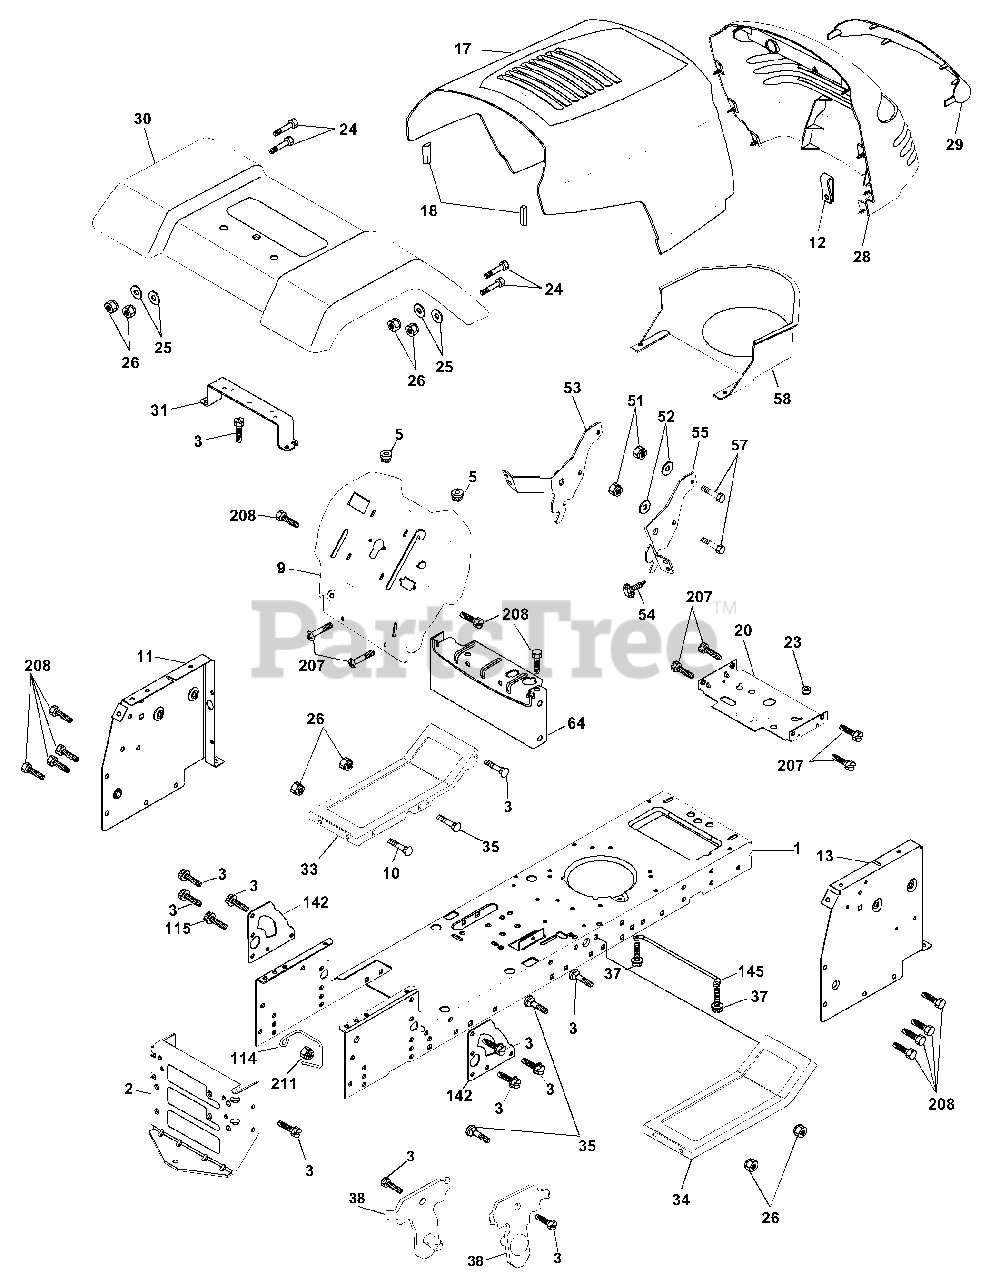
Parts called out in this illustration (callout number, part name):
1	Chassis
2	Drawbar
3	Screw 3/8-16x.75
5	Bumper Hood/Dash
9	Dash P/L
10	Bolt Carriage 3/8-16 x 1
11	Panel Dash Lh
12	Clip Tinnerman
13	Panel Dash Rh
17	Hood LT/PL
18	Bumper Hood
20	Plate Mtg Battery Fuel Tank Fr
23	Bushing
24	Bolt Fin Hex 3/8-16 x 1 Gr 5
25	Washer 13/32 X 13/16 X 12 Ga
26	Nut Lock Hex W/Ins 3/8-16 Unc
28	Grille LT/PL
29	Lens LT/PL
30	Fender Footrest STLT Pnt
31	Bracket Support Fender
33	Footrest Pnt Lh
34	Footrest Pnt Rh
35	Bolt Rdhd Sht Sqnk 3/8-16 x 3/4
37	Screw Thdrol 6/16-18 x 1/2 TYT
38	Bracket Asm. Pivot Mower Rear
51	Nut Lock Hex W/Ins 1/4-20
52	Washer 9/32 x 7/8 x 16 Ga.
53	Bracjet Grukke Lh
54	Screw Hex Wshd 8-18 x 7/8
55	Bracket Grille Rh
57	Bolt Hex 1/4-20 x 3/4
58	Duct Air
64	Dash Lower STLT
114	Keeper Belt Rear Lh
115	Screw 3/8-16 x 1-1/4
142	Plate Reinforcement STLT
145	Rod Pivot Chassis/Hood
207	Screw Thdrol 5/16-18 x 1/2
208	Screw Thdrol 3/8-16 x 1/2
211	Nut Hex Flange Lock
